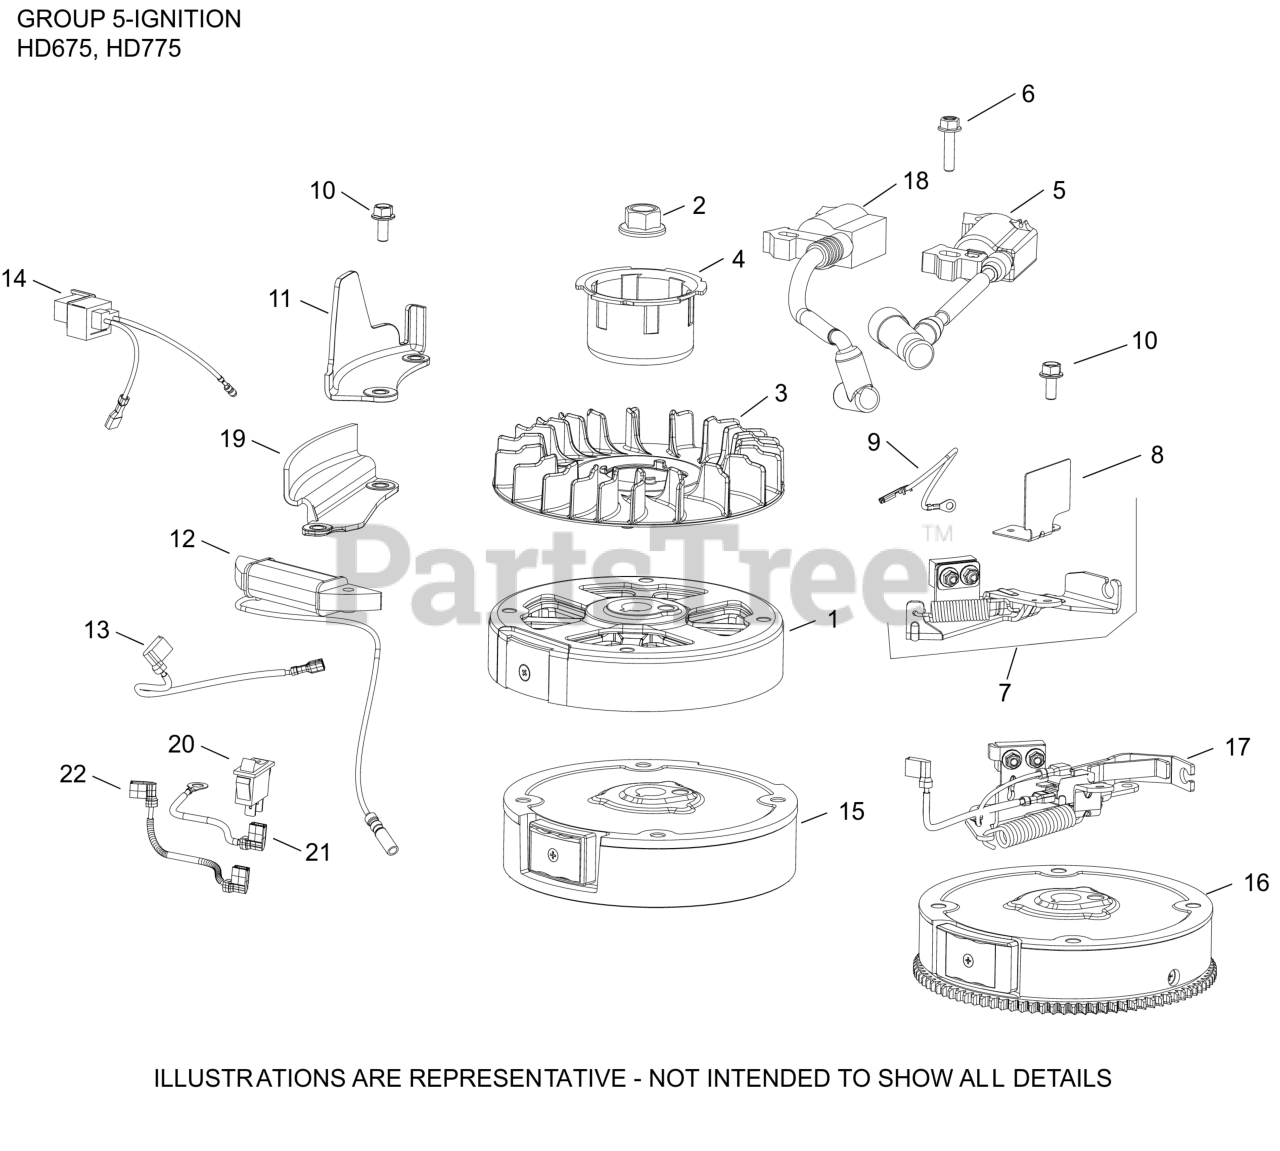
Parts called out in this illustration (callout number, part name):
2	NUT, FLYWHEEL (W/SERRATIONS)
3	FAN, FLYWHEEL
4	CUP, STARTER DRIVE
6	SCREW, M6 X 25-(#25086436S)
15	FLYWHEEL (CAST IRON)
18	MODULE IGNITION CAST IRON FLYWHEEL
